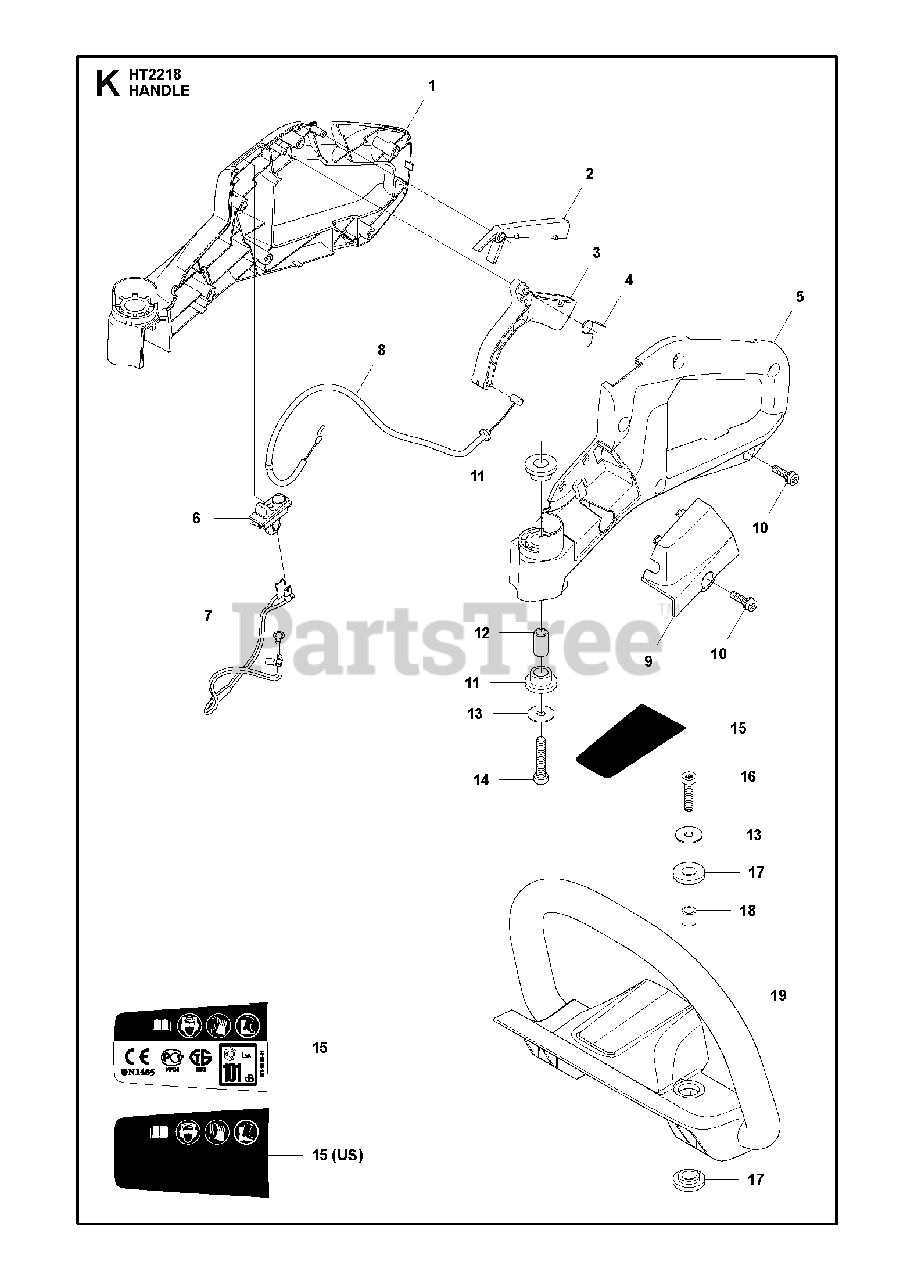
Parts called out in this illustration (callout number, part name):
1	REAR HANDLE
2	THROTTLE LOCKOUT
3	THROTTLE CONTROL
5	REAR HANDLE
6	STOP BUTTON
7	SHORT CIRCUIT CABLE
8	THROTTLE CABLE ASSY
11	ANTIVIBRATION ELEMENT
15	DECAL
17	ANTIVIBRATION ELEMENT
